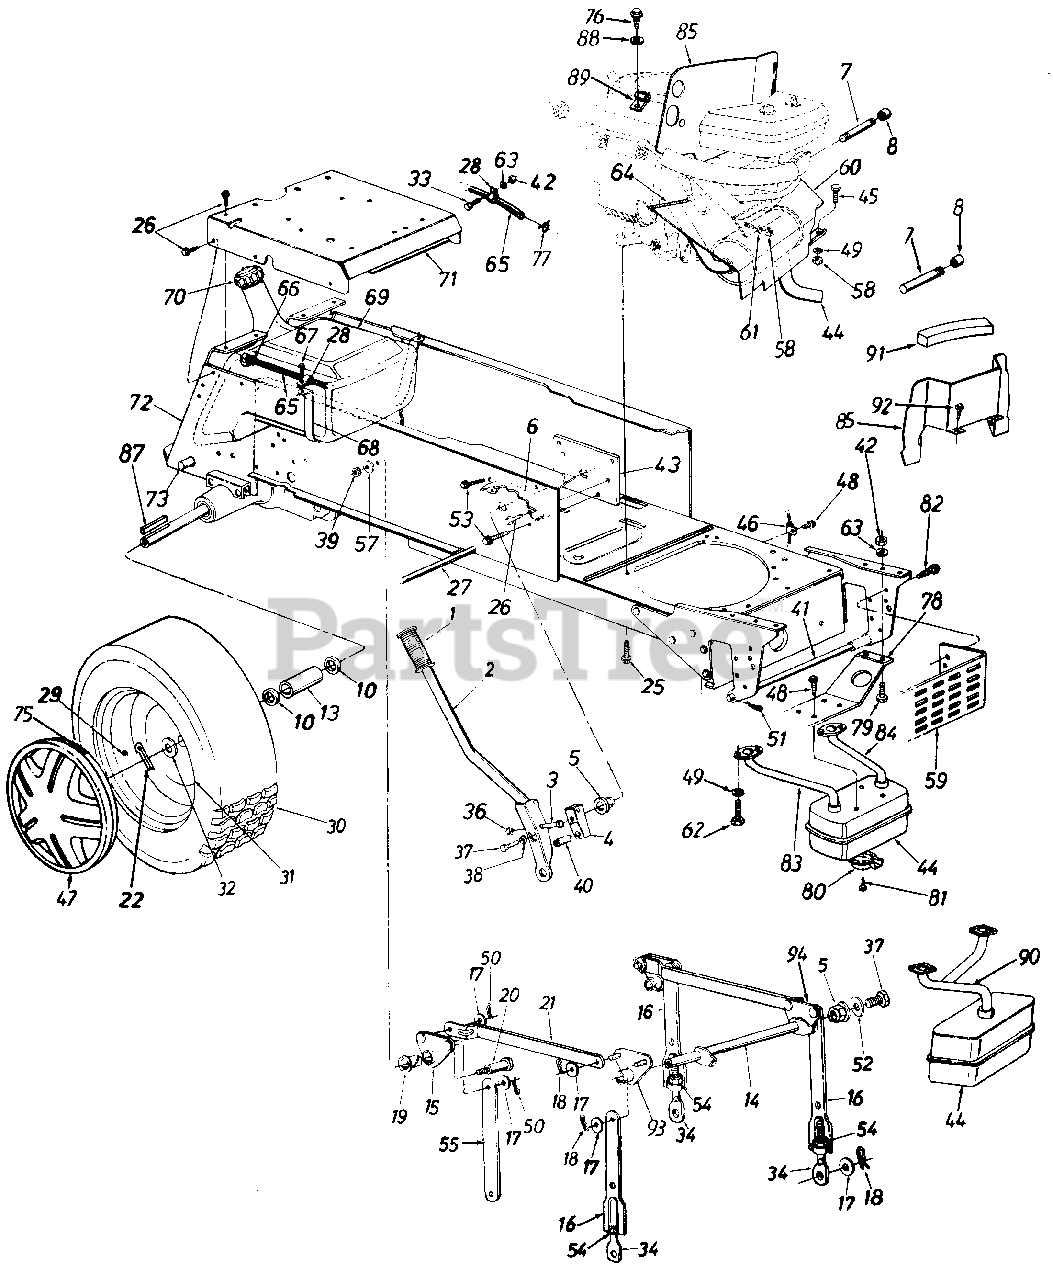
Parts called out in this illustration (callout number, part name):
1	Grip
2	Lift Handle Ass'y
3	Hex Bolt 5/16-18 x 1.5" Lg.
4	Lift Shaft Drive
5	Plastic Hex Brg. 5/8" I.D.
8	Oil Drain Cap
10	Fl-Wash. 1.03" I.D. x 1.62" O.D.
13	Spacer 1" I.D. x 1.25" O.D.
14	Lift Shaft Ass'y.
15	Lift Pivot Brkt. Ass'y.
17	Fl-Wash. 1/2" I.D. x 1.00" O.D. x .090"
18	Hairpin Cotter
19	Flange Brg. .63" I.D.
20	Shld. Bolt 5/8" Dia. x .96" LG. 3/8-16
25	Hex Wash. Hd. Scr. 3/8-16 x 1.25" Lg.
26	Hex Thd. Rolling Scr. 5/16-18
27	Running Board Rod
28	Clamp
29	Air Valve
33	Hex Bolt 1/4-20 x .62" Lg.
34	Eye Bolt Adj. Link 1/2-13 Thd.
36	Hex Cent. L-Nut 5/16-18 Thd.
37	Hex Bolt 5/16-24 x .62" Lg.
39	Hex Top L-Nut 3/8-16 Thd.
40	Compression Spring
41	Deck Connecting Rod
42	Hex Nut 1/4-20 Thd.
45	Hex Bolt 5/16-18 x .75" Lg.
46	Mounting Clamp
47	Hub Cap
48	Hex Wash. Hd. TT-Tap Scr. 1/4-20 x .5" Lg.
49	L-Wash. 5/16" I.D.
50	Cotter Pin .09 Dia. x 1.0 Lg.
51	Int. Cotter Pin
52	Flat Wash. .34" I.D. x 1.12" O.D. x .5"
53	Hex Wash. Hd. AB-Tap Scr. 5/16-24 x .5" Lg.
54	Hex Nut 1/2-13 Thd.
57	Bell-Wash. .4" I.D. x 1.13" O.D.
58	Hex Nut 5/16-18 Thd.
59	Heat Shield
60	Front Heat Shield
61	Spec. L-Wash. 5/16" I.D.
62	Cap Scr. 5/16-18 x 1" Lg.
63	L-Wash. 1/4" I.D.
64	Trim Strip 12" Lg.
65	Fuel Line 46" Lg.
66	Hose Clamp
67	Hex AB-Tap Scr. 1/4 x .62" Lg.
68	Fuel Tank Strap
69	Gas Tank
70	Gas Gauge
75	Spring Clip
76	Truss Mach. B-Tap Scr. #10 x .5" Lg.
77	Hose Clamp
78	Muffler Mounting Brkt.
79	Hex Bolt 1/4-20 x .85" Lg.
80	Muffler Deflector
81	Hex Wash. Hd. F-Tap Scr. #8 x .32" Lg.
82	Hex Wash. Hd. TT-Tap Scr. 5/16"-18 x .62" Lg.
83	Exhaust Tube - R.H.
84	Exhaust Tube - L.H.
87	Sq. Key 1/4" x 3" Lg.
88	Fl-Wash. .188" I.D. x .438" O.D.
89	Clamp
90	Exhaust Pipe
91	Foam Seal
92	Hex Wash. Hd. #8-32 x .5" Lg.
93	Pivot Brkt. Ass'y. - R.H.
94	Pivot Brkt. Ass'y. - L.H.
